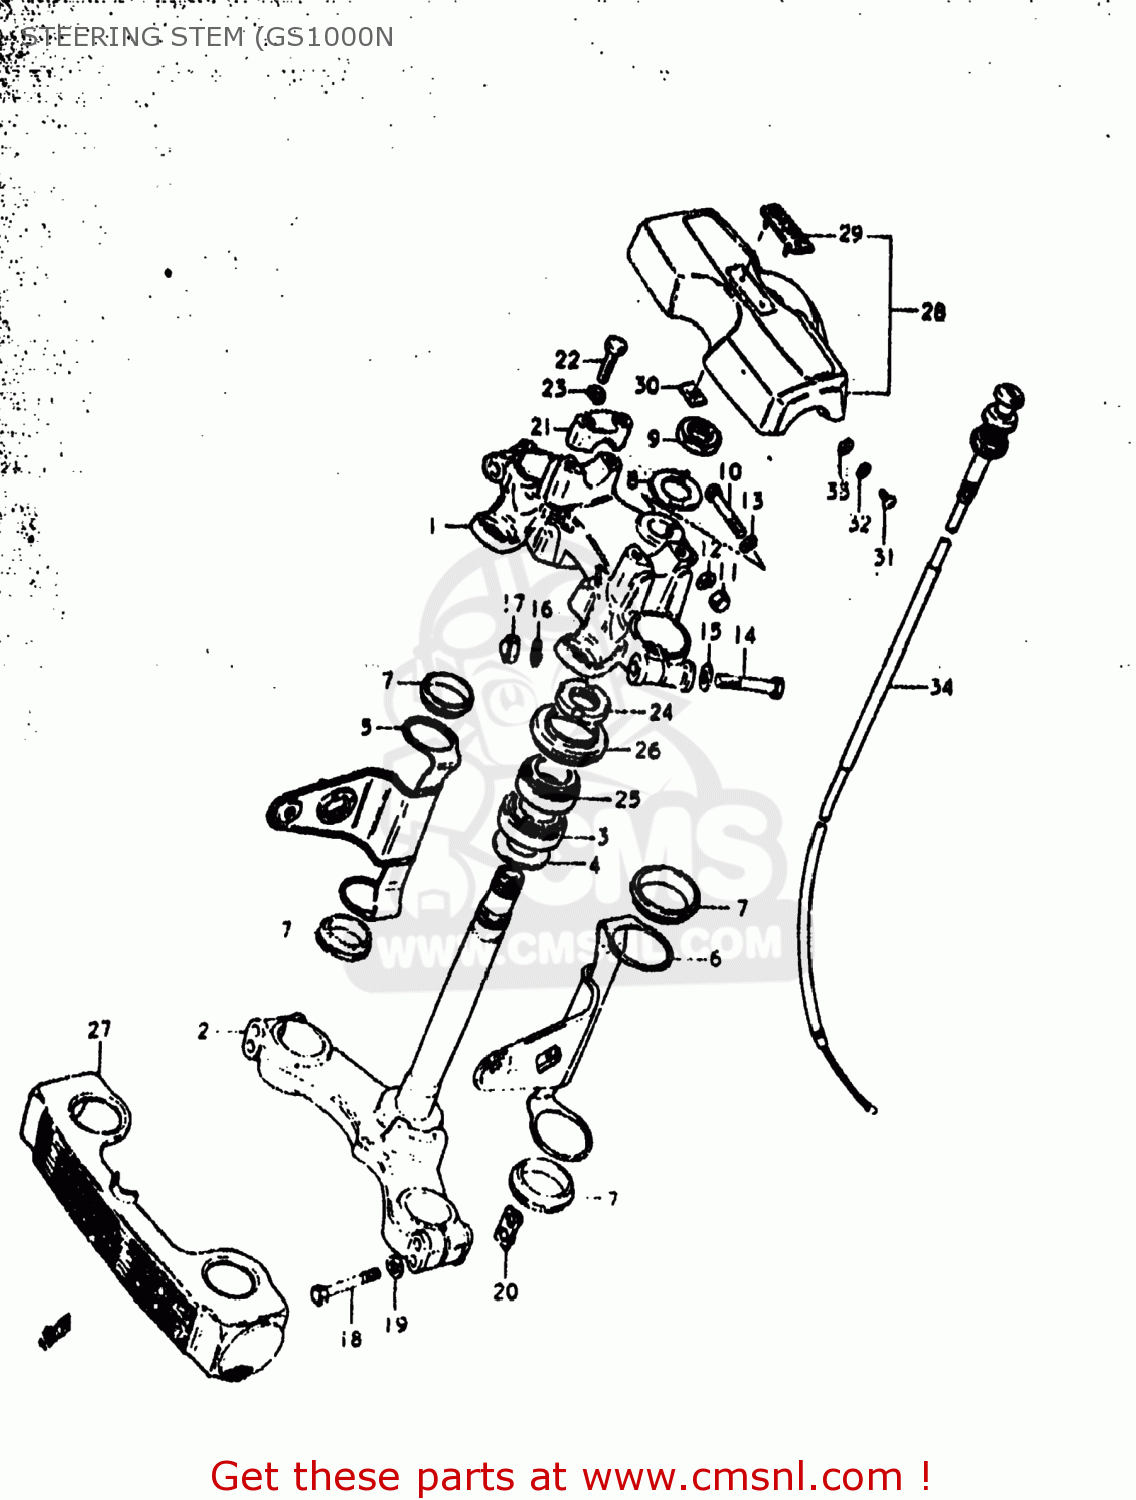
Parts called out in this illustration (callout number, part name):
1	HEAD,STEERING STEM
2	STEM,STEERING
3	BEARING
4	WASHER,THRUST
5	BRACKET,HEADLAMP,RIGHT
6	BRACKET,HEADLAMP,LEFT
7	CUSHION,HEADLAMP BRACKET
8	WASHER
9	NUT,FR FORK UPR BRACKET
10	BOLT 8X50
11	NUT
12	LOCK WASHER
13	WASHER
14	BOLT 10X55
15	WASHER
16	LOCK WASHER
17	NUT, LOWER LH
18	BOLT 8X55
19	WASHER
20	NUT,FR FORK INNER TUBE
21	HOLDER,HANDLE(BLACK)
22	BOLT
23	LOCK WASHER
24	NUT,STEERING STEM(25X44X10)
25	TAPER,ROLLER BEARING
26	DUST SEAL,STEERING,UPPER
27	COVER,FRONT FORK
28	PAD,HANDLEBAR
29	EMBLEM,HANDLE COVER PAD
30	NUT
31	SCREW
32	LOCK WASHER
33	WASHER
34	CABLE ASSY,STARTER
